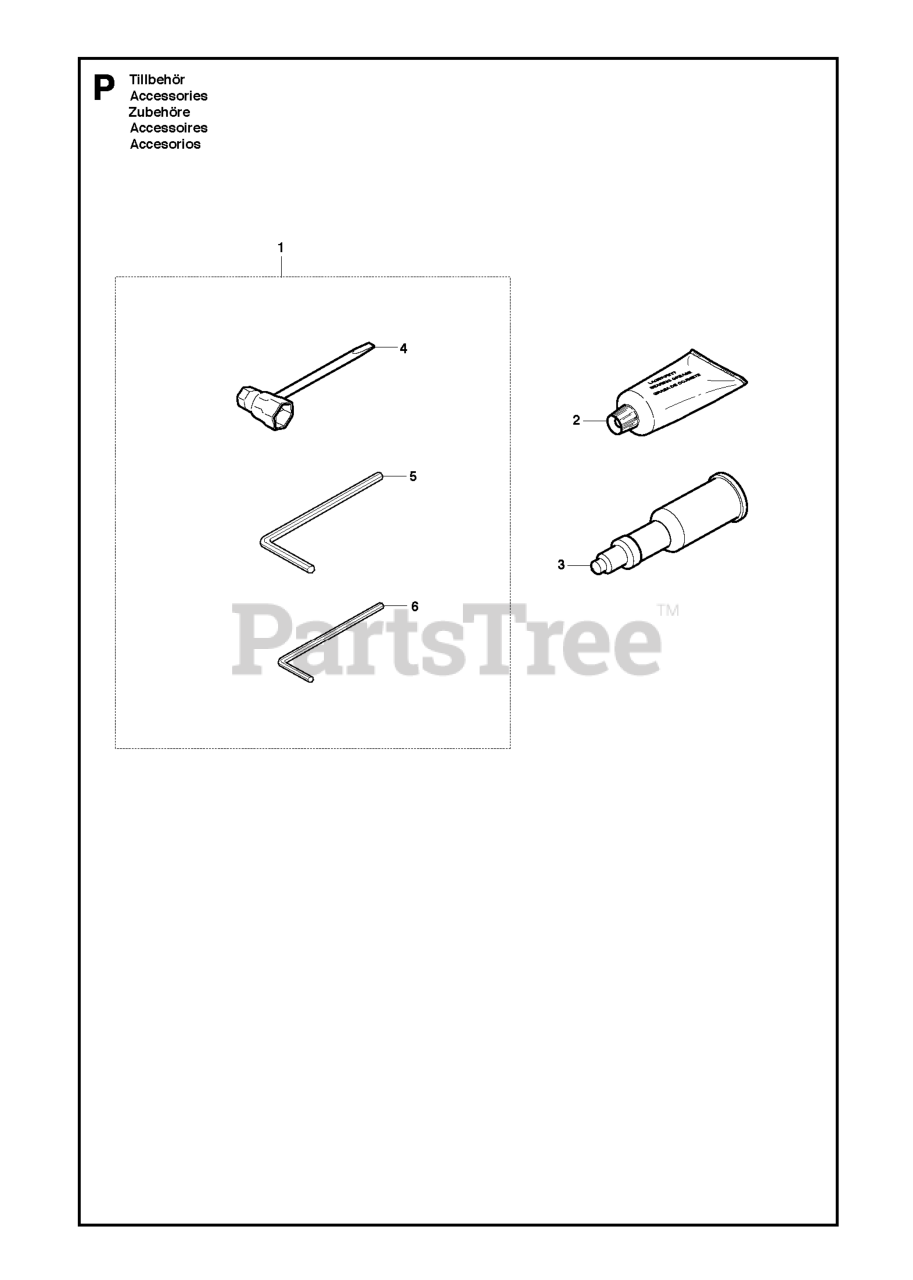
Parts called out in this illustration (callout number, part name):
1	TOOL KIT
2	GREASE
3	Grease Gun
4	COMBI TOOL
